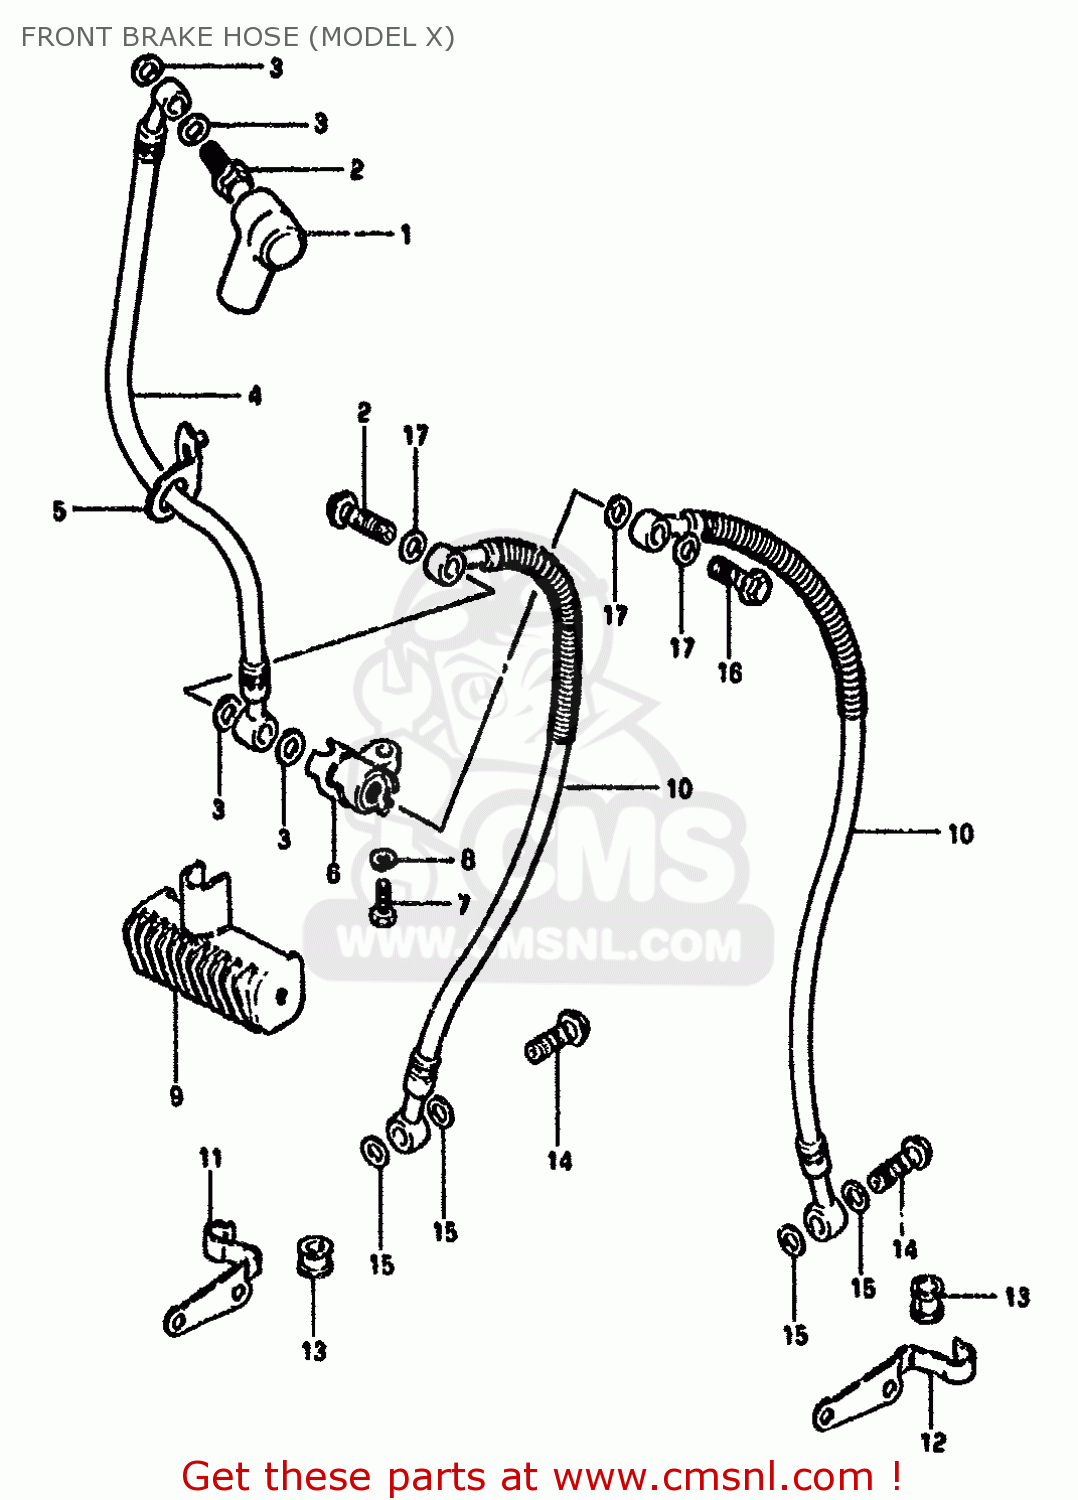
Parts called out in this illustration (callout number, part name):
1	BOOT,MASTER CYLINDER
2	BOLT,UNION
3	WASHER
4	HOSE,FRONT BRAKE
5	GUIDE,BRAKE HOSE NO.1
6	JOINT,BRAKE HOSE
7	BOLT
8	LOCK WASHER
9	COVER,BRAKE HOSE JOINT
10	HOSE,FRONT BRAKE
11	CLAMP,FRONT BRAKE HOSE
12	CLAMP,FRONT BRAKE HOSE
13	BUSH,BRAKE HOSE GUIDE,NO.2
14	BOLT,UNION
15	WASHER
16	BOLT,UNION
17	WASHER
